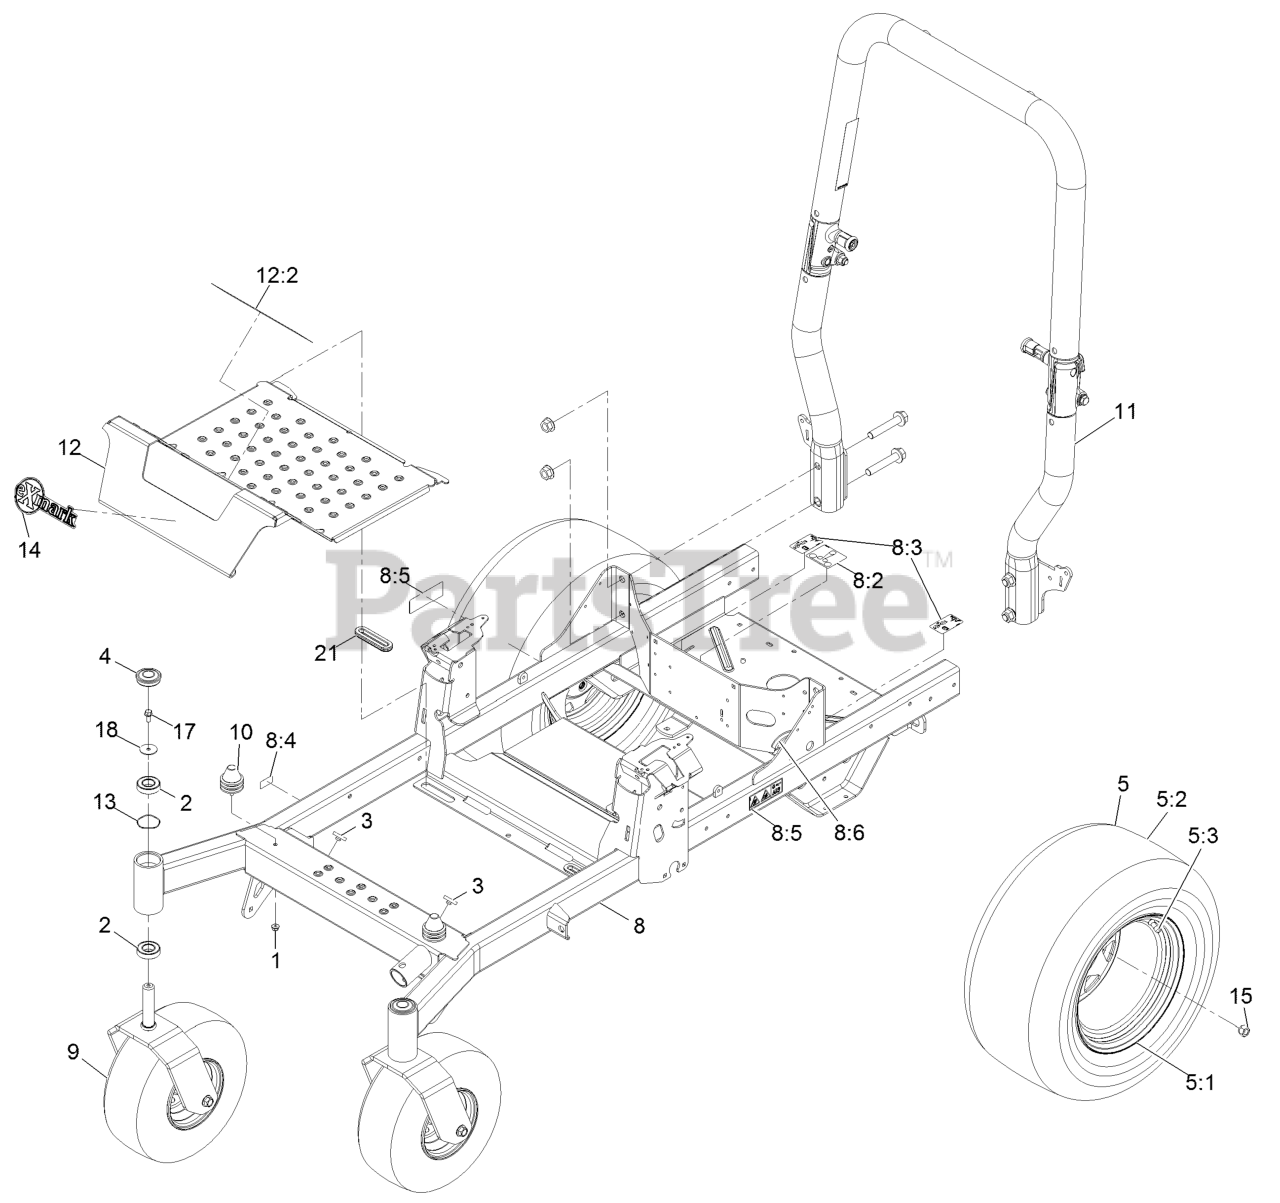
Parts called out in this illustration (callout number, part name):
1	NUT-HF, NI
2	BEARING-BALL
3	BUMPER-PUSH-IN, RUBBER
4	CAP-GREASE
5	WHEEL AND TIRE ASM
5:1	WHEEL RIM 12X8.5
5:2	TIRE
5:3	Stem-Valve
8	FRAME ASM
8:2	DECAL-ROUTING, BELT
8:3	DECAL-RELEASE, DRIVE
8:4	Decal-Patent
8:5	DECAL-WARNING
8:6	STRIP-SEAL
9	ASM-Front Caster W/Fork
10	ISOLATOR
11	ASM-ROPS TAPERED
12	PAN-FLOOR
12:2	DECAL-DANGER
14	DECAL-EXMARK LOGO
15	NUT-LUG
17	SCREW-HHF
18	WASHER-FLAT
21	GROMMET-RUBBER
